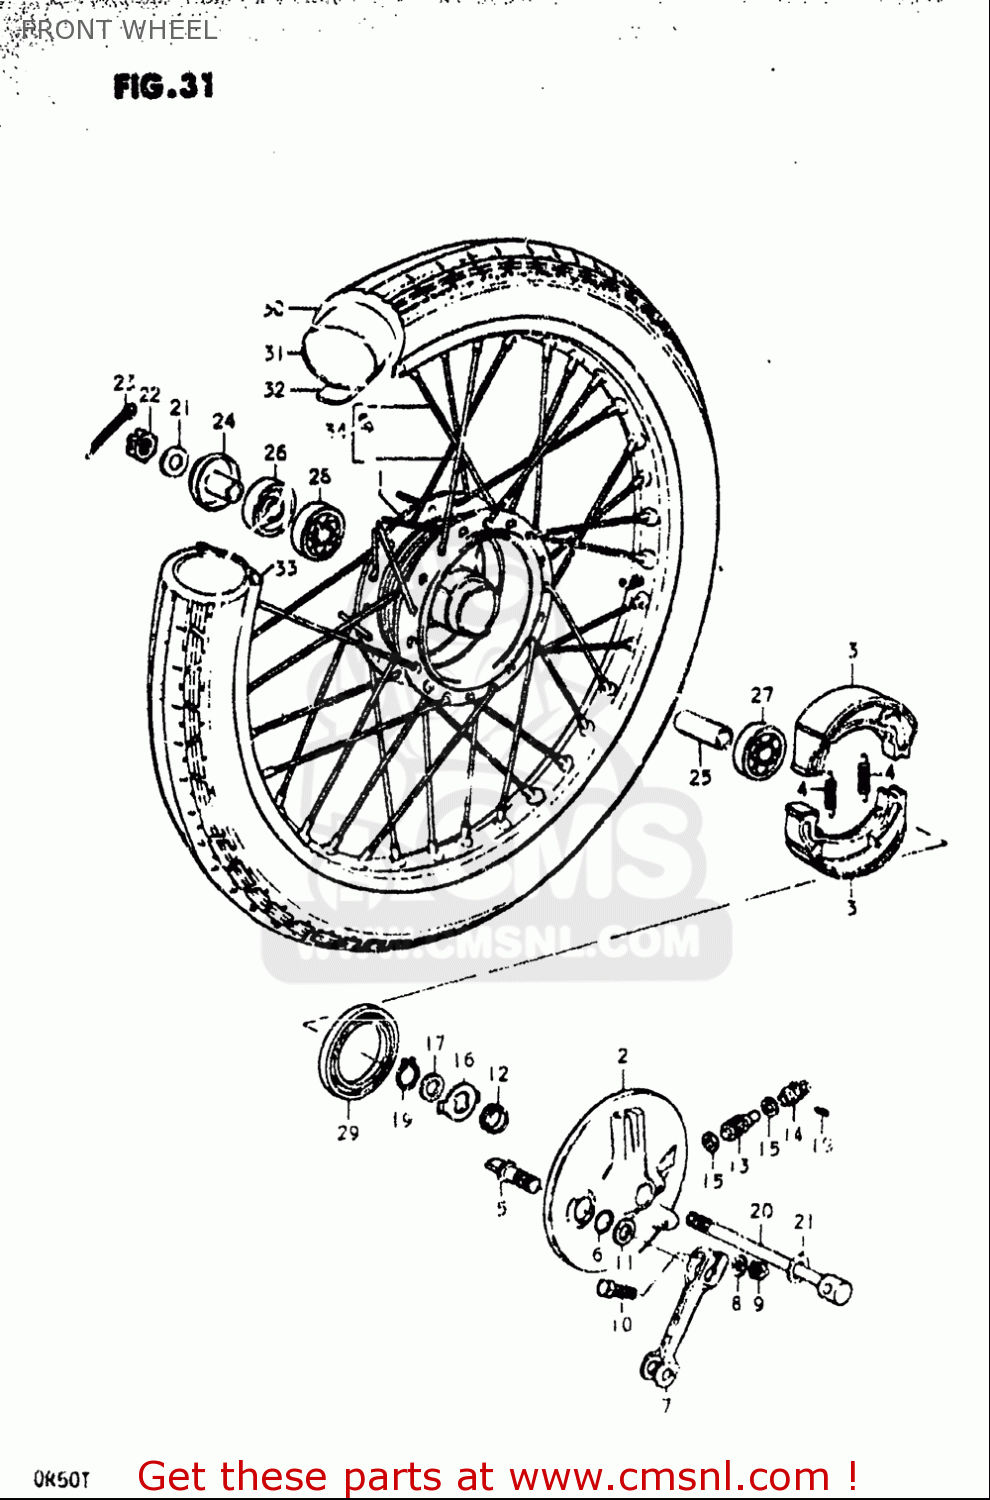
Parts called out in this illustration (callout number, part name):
1	HUB,FR WHEEL
2	PANEL,FR BRAKE ANCHOR
3	SHOE & SPRING SET,BRAKE (NAS)
4	SPRING(L:35.8)
5	CAM,BRAKE
6	O RING(D:2.5,ID:13.8)
7	LEVER,FR BRAKE CAM
8	WASHER
9	NUT
10	BOLT(6X33)
11	WASHER(14.5X22X1.6)
13	PINION,SPEEDOMETER
15	WASHER(5.1X9X0.4)
17	WASHER(16X22X1)
18	SCREW
19	CIRCLIP
20	AXLE,FRONT
21	WASHER(10.5X22X2.3)
22	NUT
23	PIN
24	SPACER,FR AXLE,R
25	SPACER(10.1X16X51)
26	SEAL,OIL(15X31X5)
27	BEARING
28	BEARING
29	SEAL,OIL(43X58X7)
33	RIM,FRONT WHEEL
